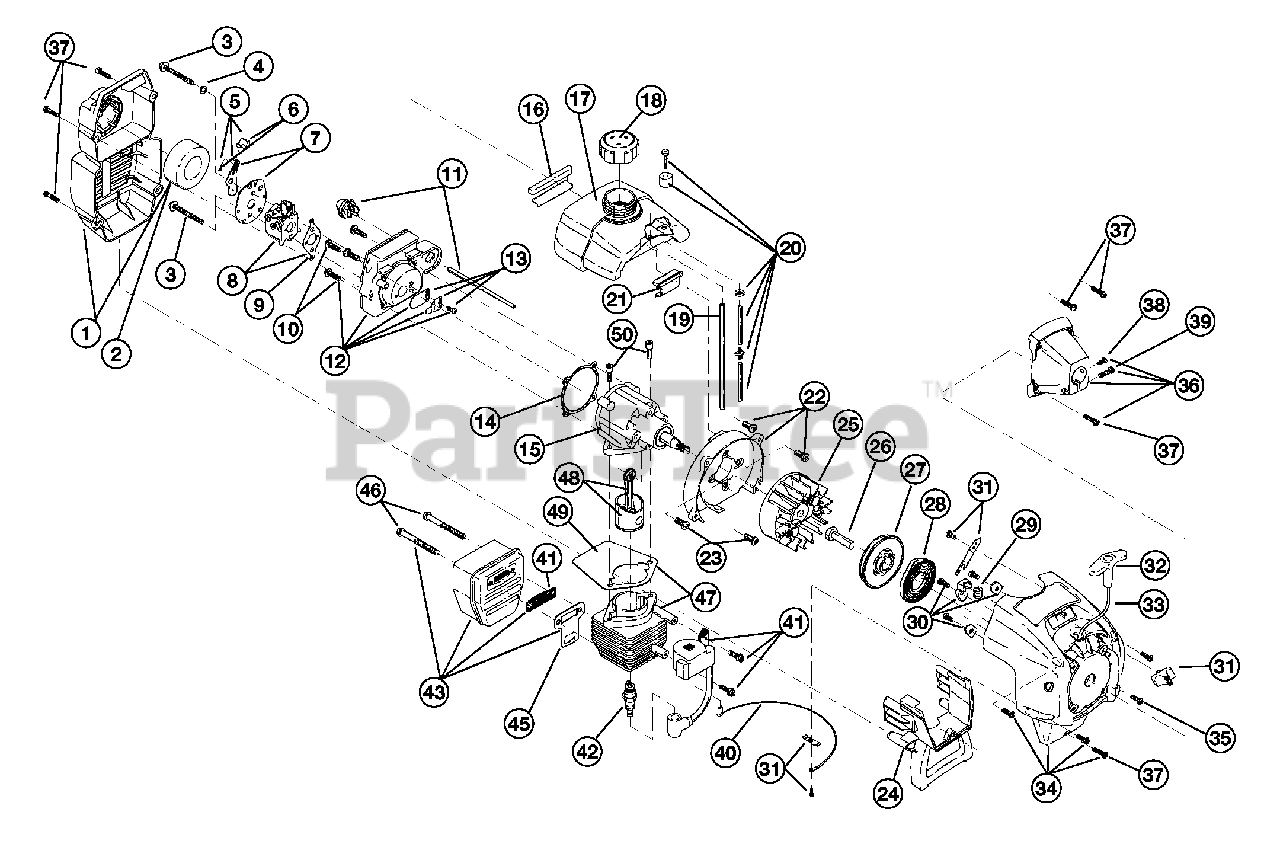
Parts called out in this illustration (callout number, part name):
1	Air Cleaner/Muffler Cover Assembly
2	Air Cleaner Filter
3	Carburetor Mounting Screw Assembly
4	Wavey Washer
5	Choke Lever Assembly
6	Choke Knob and Screw
7	Choke Lever and Plate
8	Carburetor Assembly
9	Carburetor Gasket
10	Carb Mount Screw
11	Primer and Hose Assembly
12	Carb Mount Assembly
13	Reed Assembly
14	Carburetor Mount Gasket
15	Crankcase Service Assembly
16	Rear Mounting Pad
17	Fuel Tank Assembly
18	Fuel Cap Assembly
19	Fuel Return Line
20	Fuel Line Assembly
21	Front Mounting Pad
22	Shroud Assembly
23	Shroud Screw
24	Shroud Extension & Stand
25	Flywheel Assembly
27	Recoil Pulley Assembly
28	Recoil Spring
29	Rope Guide
30	Pulley Retainer Assembly
31	Switch Assembly
32	Pull Handle
34	Starter Housing Assembly
35	Housing Screw
36	Clutch Cover Assembly
37	Cover Screw
38	Anti-Rotation Screw
39	Clamping Screw
40	Wire Lead
41	Module Assembly
42	Spark Plug
43	Muffler Assembly
44	Spark Arrestor Screen
45	Exhaust Gasket
46	Muffler Mounting Bolt Assembly
47	Cylinder Assembly
48	Piston and Rod Assembly
49	Cylinder Gasket
50	Cylinder Bolt
